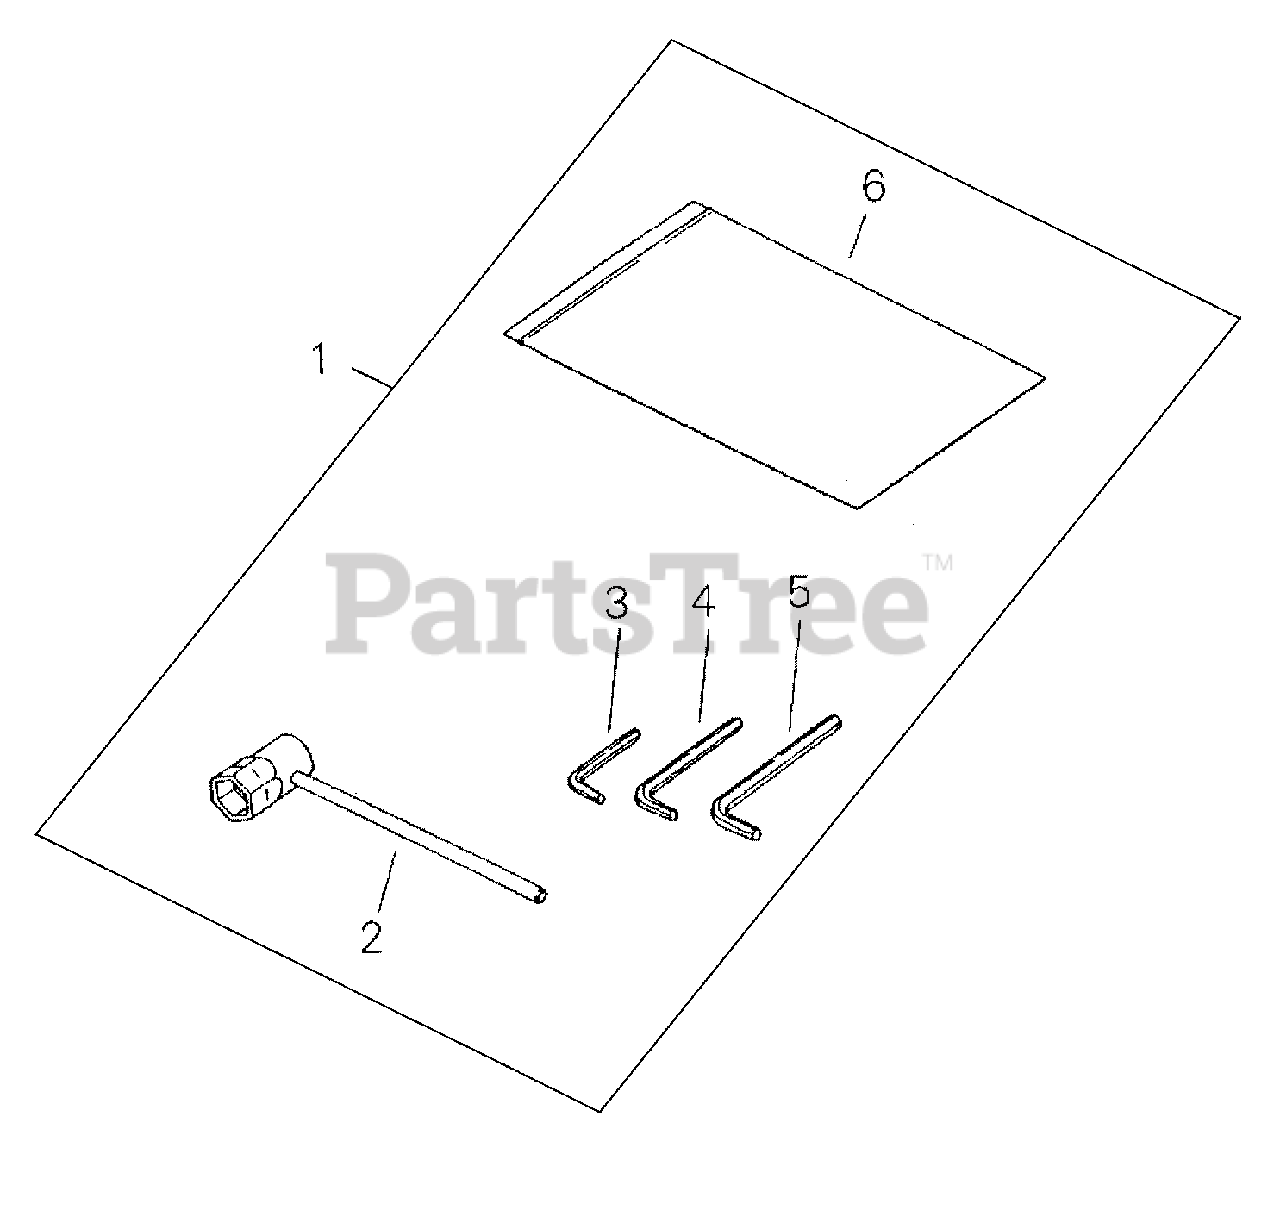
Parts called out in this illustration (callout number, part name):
1	TOOL KIT, SERVICE
2	T-WRENCH 19 MM
3	WRENCH, ALLEN 3 MM
4	WRENCH, ALLEN 4 MM
5	WRENCH, ALLEN 5 MM
6	BAG, TOOL
